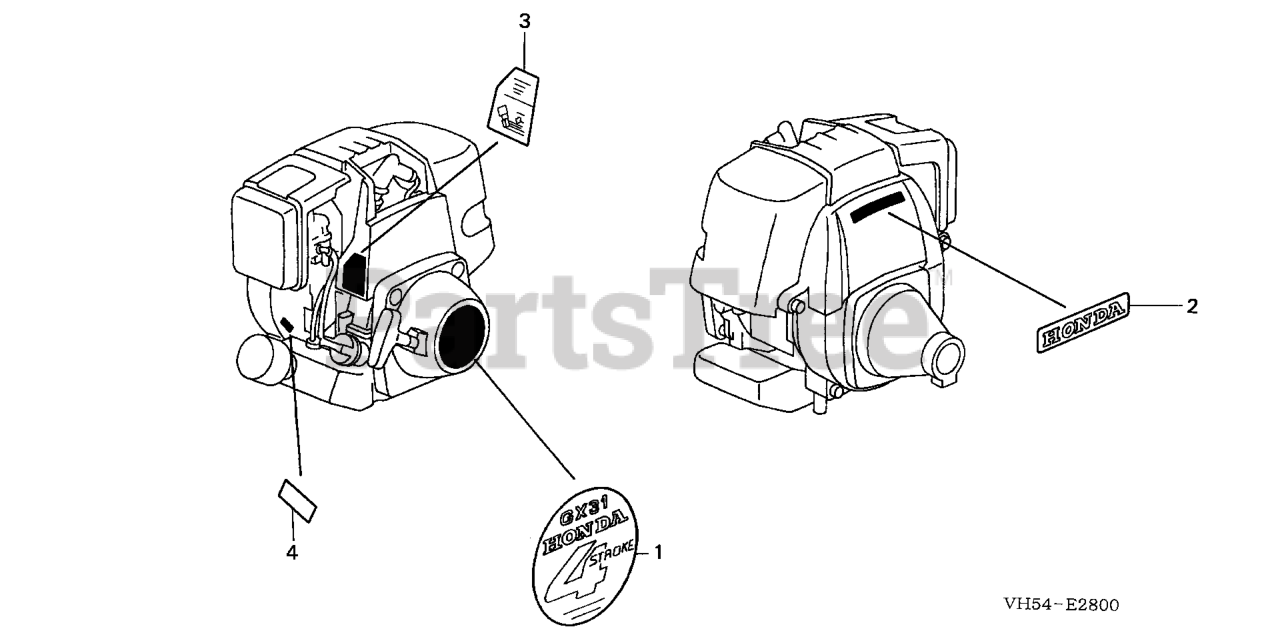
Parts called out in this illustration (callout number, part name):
1	EMBLEM (GX31)
2	MARK, HONDA
3	MARK, OIL CAUTION (ENGLISH)
4	MARK, TYPE (GD2)
